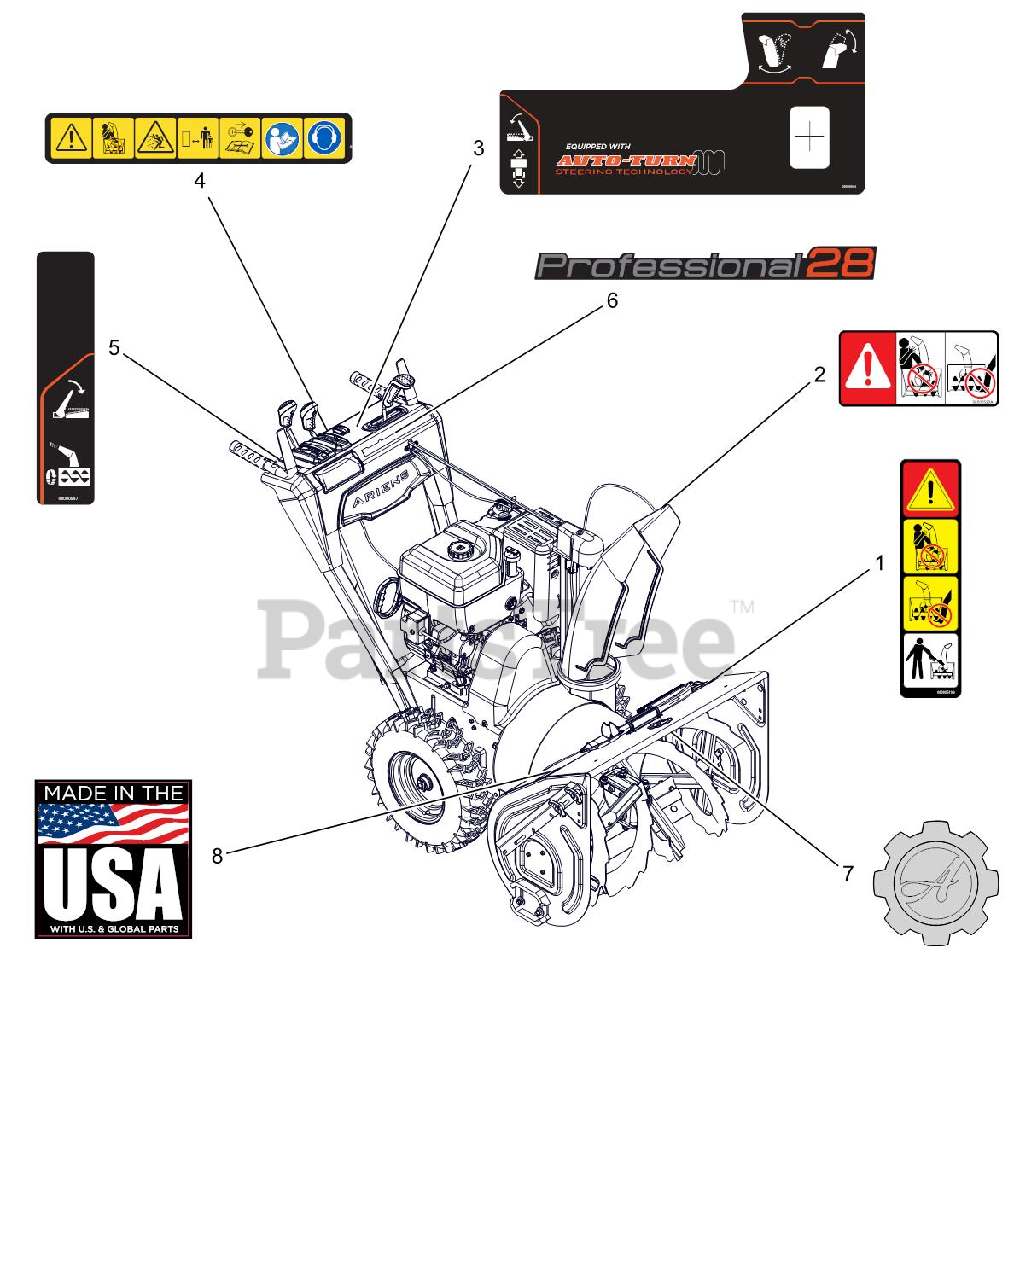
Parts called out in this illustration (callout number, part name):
1	DECAL, DANGER - ROTATING PARTS
2	DECAL, DANGER
3	DECAL,CONTROL-LG QT2
4	DECAL,DASH - SAFETY
5	DECAL,CONTROL-RH CONTROL
6	DECAL, DASH - PRO 28
7	DECAL, ARIENS-GEAR BADGE
8	DECAL, MADE IN USA
